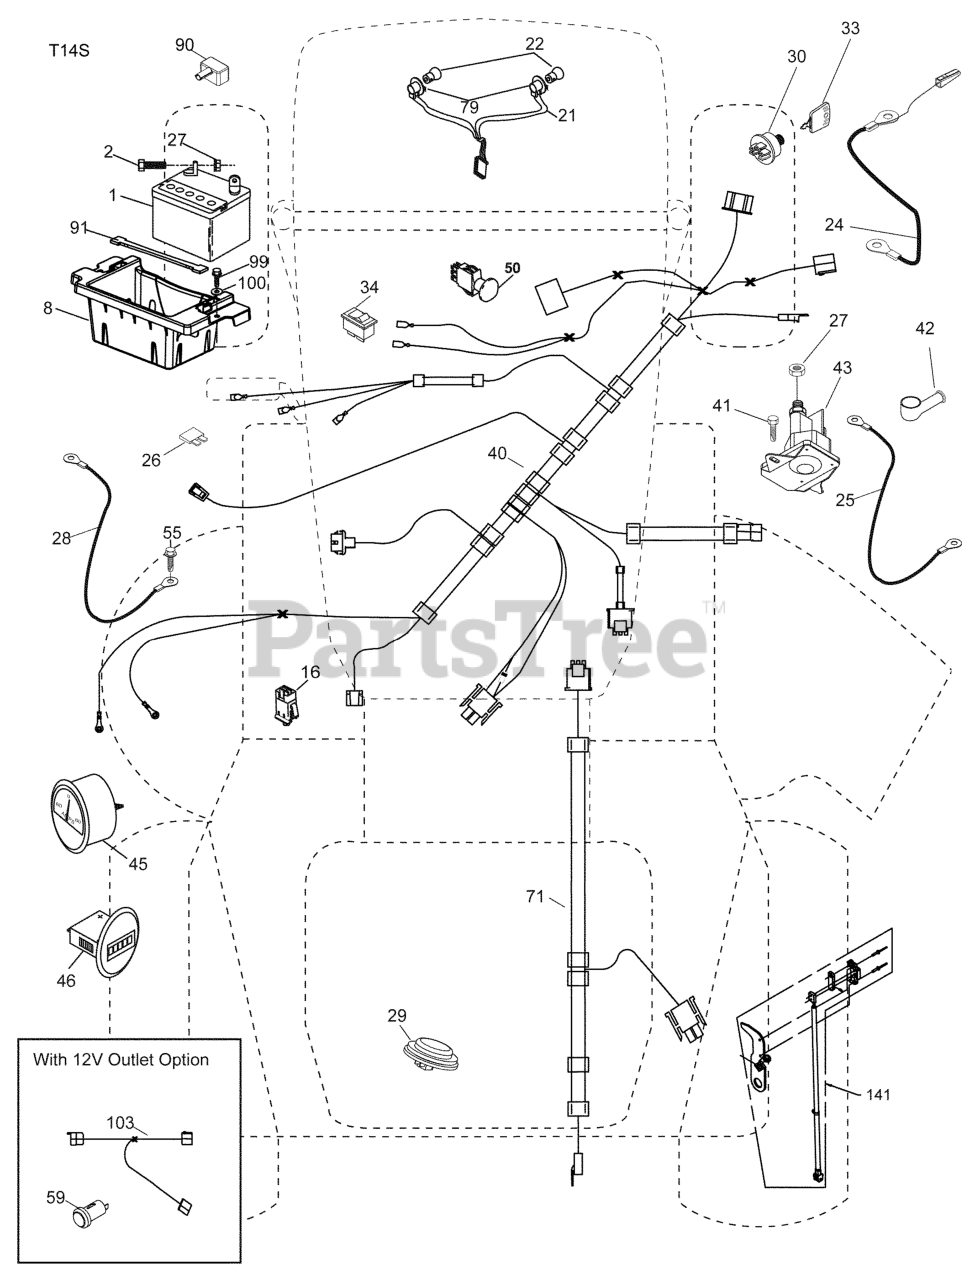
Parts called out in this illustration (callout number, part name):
1	Battery
2	BOLT.HEX.1/4.X.3/4.DICHROMATE
8	TRAY.ASM.BATTERY.FRT.TEX.CARB
16	SWITCH INTERLOOK PUSH-IN
21	HARNESS ASSY LIGHT
24	CABLE.BATT.POS.WIRE.TG.DA SOL
25	CABLE.STARTER.6G.BL/RED.17.5
26	FUSE 20AMP
27	NUT
28	CABLE GROUND 6 GA 21" 90T BLK
29	SWITCH.SEAT.DELTA.OPC.
30	SWITCH.IGN.DELTA.W.LGH.ROS
33	KEY.CHAIN.BLISTER.PACK.GEN.INT
40	HARNESS IGN. DASH
41	SCREW
42	TERMINAL COVER
43	SOLENOID.W/BRASS.PLUNGER
45	AMMETER GAUGE ROUND SNAP-IN
46	HOURMETER.GAUGE.RNK.SNAP.LS
50	RP.PTO.SWITCH.8 TERMINAL.BLACK
55	SCREW 5/16"
59	OUTLET.12-VOLT
71	HARNESS-CHASSIS SUB
79	BULB HOLDER ASM.
90	COVER.TERMINAL.BATTERY
91	STRAP.BATTERY.MOUNT.FRONT(2 2)
99	SCREW HEXWSHR 1/4-20X3/4
100	WASHER
103	HARNESS.PIGTAIL.12V.OUTLET.
141	KIT.G700/G730.ROS 71750
